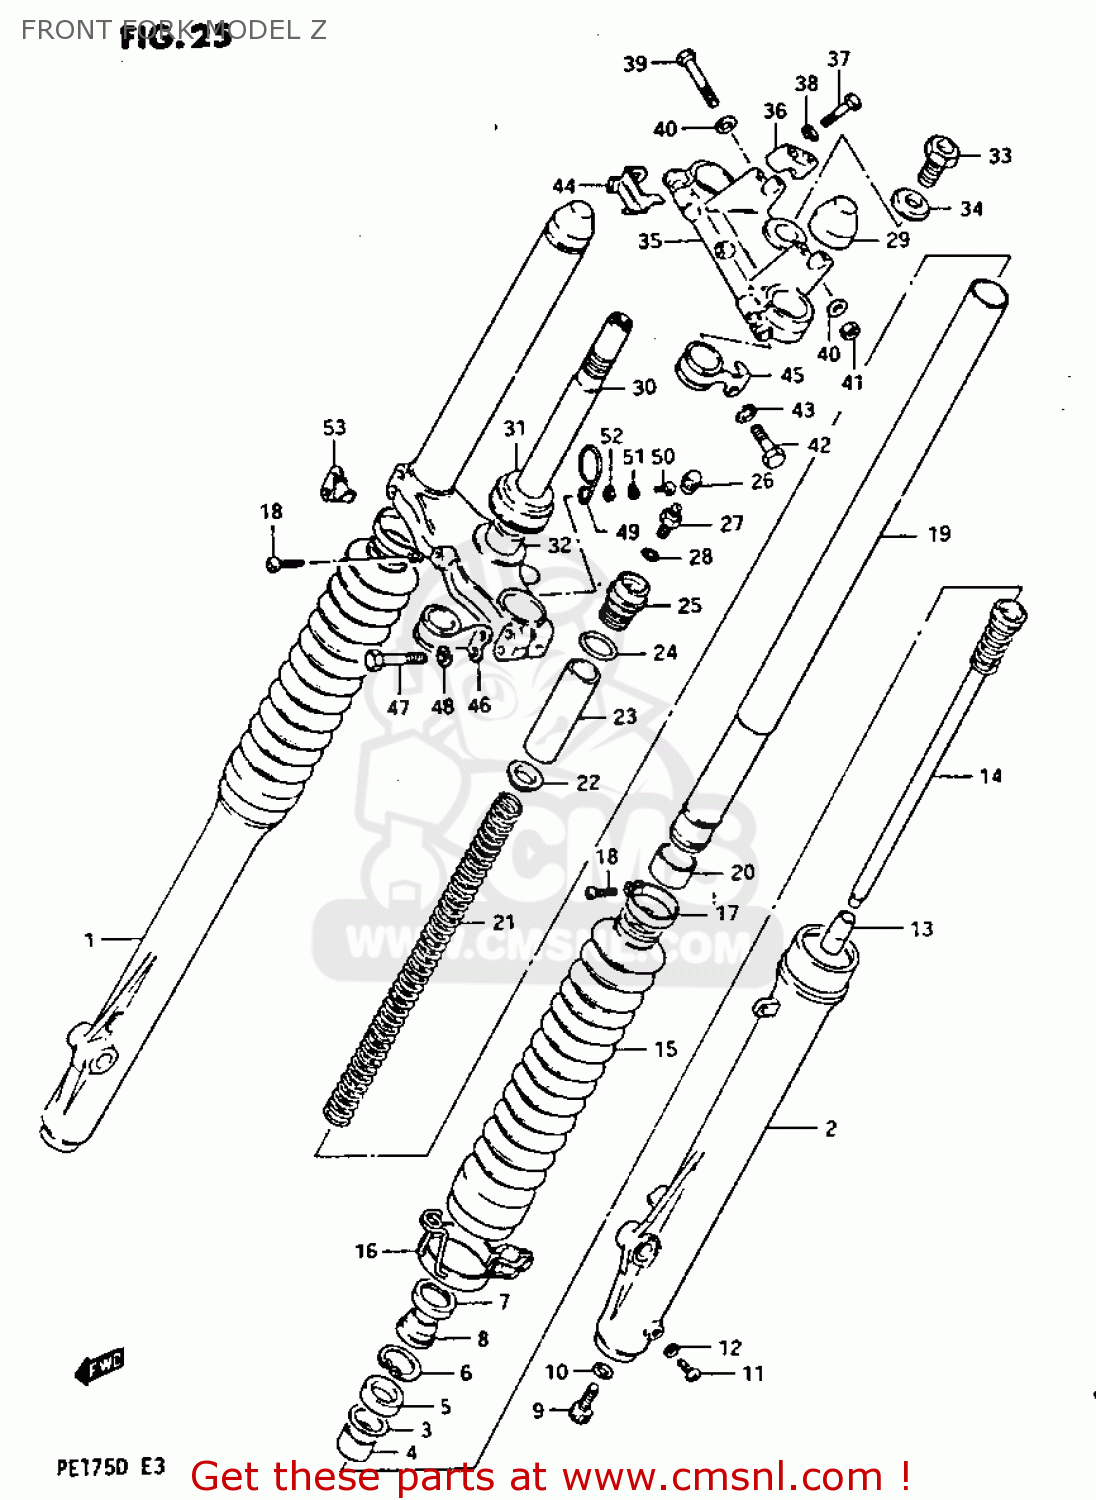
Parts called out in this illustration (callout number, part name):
1	DAMPER SET
2	TUBE,OUTER,LEFT
3	WASHER(40X50X2.3)
4	METAL,SLIDE
5	SEAL,OIL
6	RING,STOPPER
7	CASE,DUST SEAL
8	SEAL,DUST
9	BOLT,CYLINDER
10	GASKET,CYLINDER (NAS)
11	SCREW
12	GASKET,DRAIN,PLUG (NAS)
13	PIECE,OIL LOCK
14	CYLINDER,FRONT FORK
15	BOOT
16	BAND,FORK COVER BOOT
17	BAND,BOOT
18	SCREW
19	TUBE,FORK,INNER
20	PISTON
21	SPRING,FRONT FORK
22	GUIDE
23	SPACER
24	O RING
25	CAP,FORK INNER TUBE
26	CAP,VALVE
27	VALVE,FRONT FORK AIR
28	O-RING
29	CAP
30	STEM,STEERING
31	BEARING(30X55X17)
32	WASHER,THRUST
33	BOLT
34	WASHER
35	HEAD,STEERING STEM
36	HOLDER,HANDLEBAR
37	BOLT
38	LOCK WASHER
39	BOLT 8X50
40	WASHER
41	NUT
42	BOLT
43	WASHER,LOCK,10
44	BRACKET,TOOL FITTING,UPPER
45	GUIDE,CABLE
46	CLIP,CABLE
47	BOLT 8X45
48	LOCK WASHER
49	CLIP
50	SCREW
51	WASHER,LOCK
52	WASHER
53	BRACKET,TOOL FITTING,LOWER
